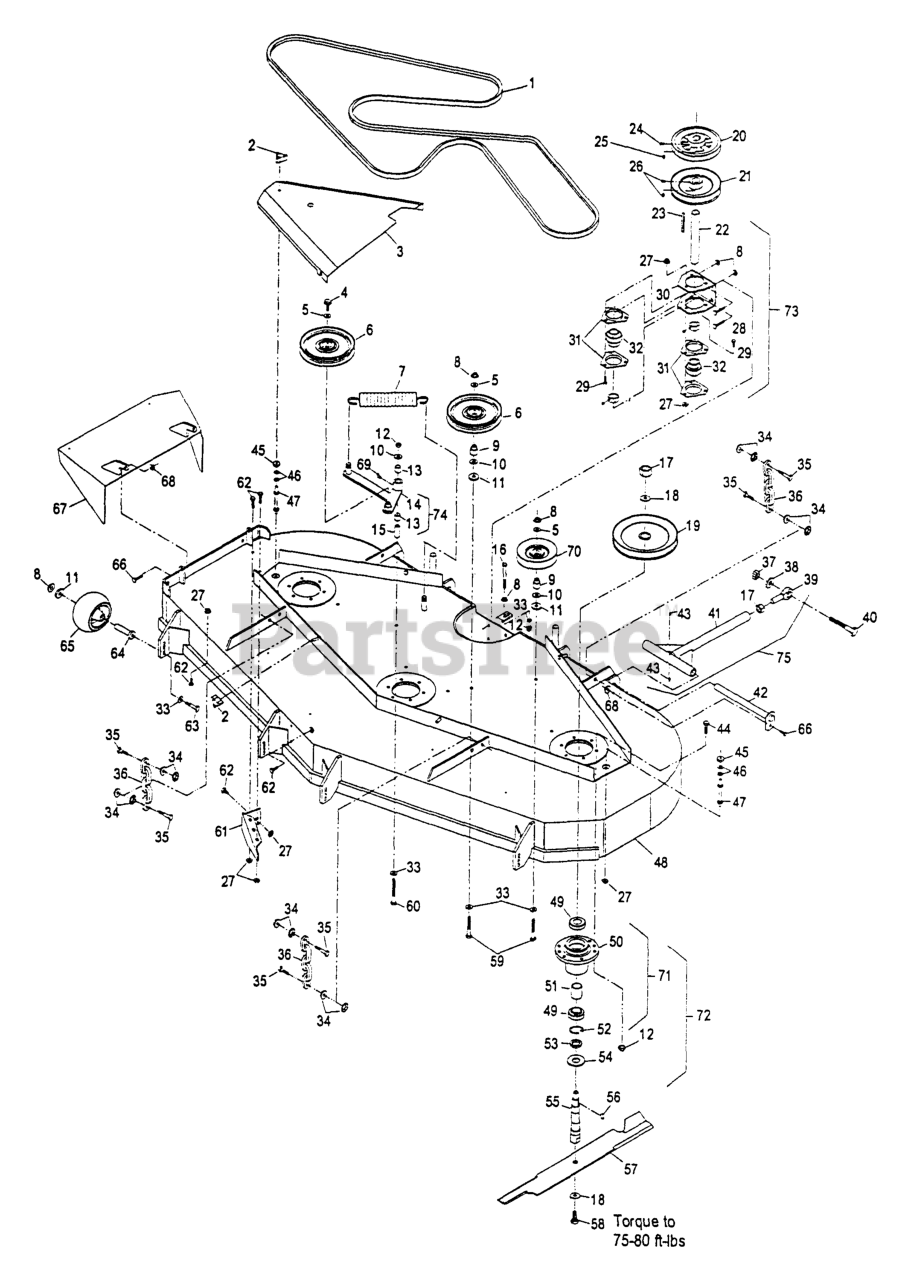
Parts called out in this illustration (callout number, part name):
1	BELT-V
2	KNOB-3 PRONG
3	SHIELD,BELT RH
9	BUSHING-IDLER
13	SLEEVE-BEARING
15	BUSHING
18	WASHER-SPRING
19	SHEAVE,BLADE DRIVE7.5EOD
20	SHEAVE,BLADE DRIVE
21	SHEAVE,SPLIT STEEL
22	JACKSHAFT,DECK DRIVE
23	KEY,MACH 1/4X1/4X2-5/8
25	SCREW-SET
26	SCREW-SET
30	BRACKET,JACKSHAFT
31	HOUSING-FLANGE
32	BEARING,W/COLLAR
35	SCREW-CAP, HH
36	CHAIN-LIFT, DECK
39	BALLJOINT-SPHERICAL
42	PIN-STRUT
47	STUD-SHIELD, BELT (SHORT)
49	BEARING
51	SPACER-BEARING
53	SPACER-PULLEY/BEARING
54	GUARD-BEARING, BOTTOM
61	WLD,BAFFLE DISCHARGE
64	BUSHING-ROLLER
65	ROLLER-SCALP, ANTI
67	WLD,CHUTE 72
70	PULLEY-IDLER
72	SPINDLE HSG ASSYCOMP72
73	DK DR. BRG. ASSY
